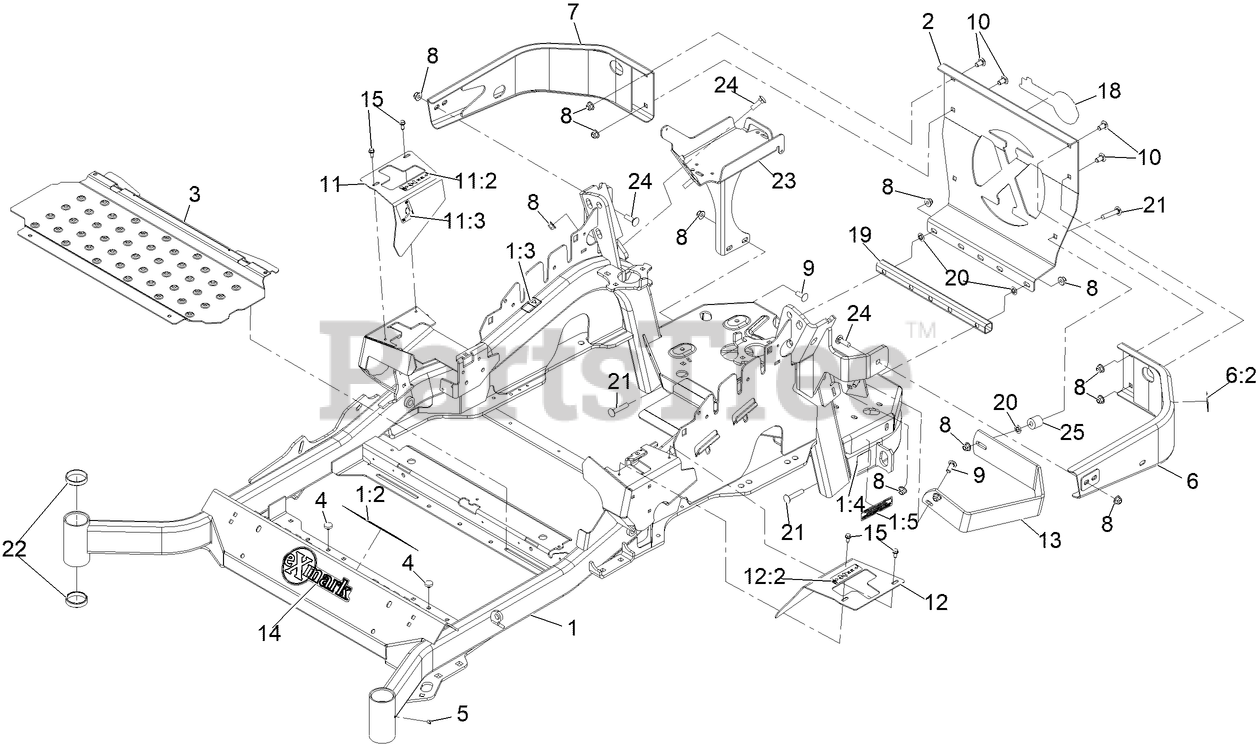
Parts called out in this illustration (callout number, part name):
1	MAINFRAME SERVICE ASM - 60
1:2	DECAL-DANGER
1:3	DECAL-WARNING
1:4	DECAL-HAZARD, PINCHED FINGER
1:5	DECAL-ARRESTOR, SPARK
2	PLATE,REAR GUARD
6	ASM-BUMPER REAR LH W/DECAL
6:2	DECAL-WARNING
7	WELD-BUMPER RH DBL HOLE
8	NUT-HF, NI
9	SCREW-CARR
10	SCREW-CARR
11	RH MOTION CONTROL COVER ASM
11:2	DECAL-CONTROL, MOTION
11:3	DECAL-PARK BRAKE, CE
12	LH MOTION CONTROL COVER ASM
12:2	DECAL-CONTROL, MOTION
13	GUARD-MUFFLER
14	DECAL-EXMARK
15	SCREW-HWH
18	DECAL, EXMARK LOGO
19	Spacer-Rear Guard Lower
20	NUT-PUSH
21	BOLT-CARRIAGE
22	CUP-BEARING
23	BATTERY MOUNT ASM
24	BOLT-CARR
